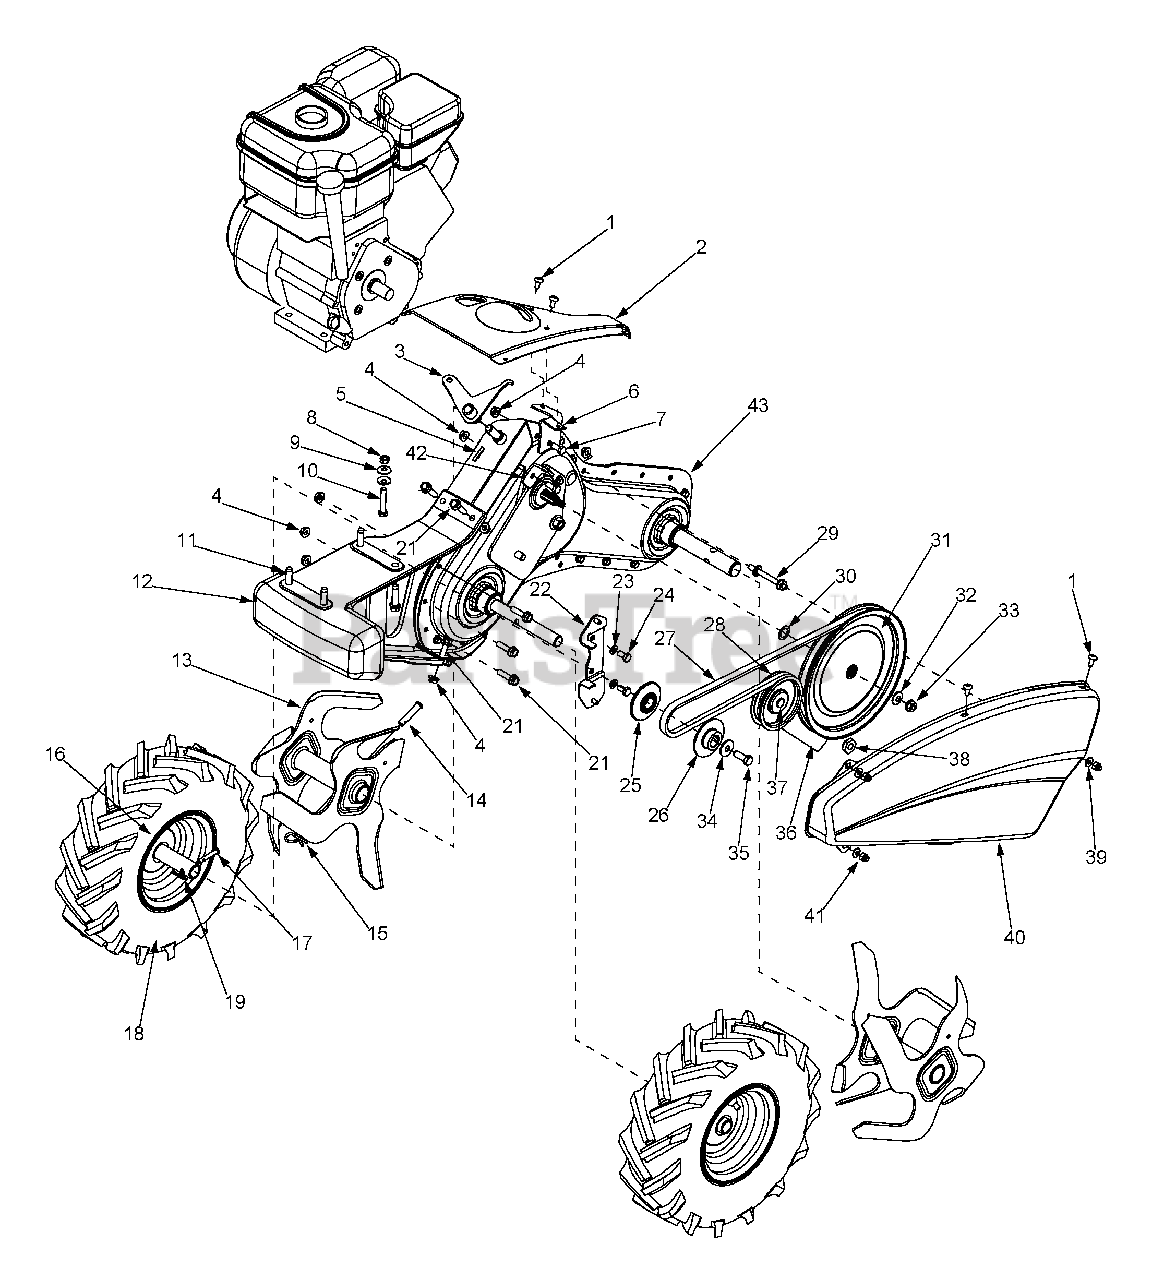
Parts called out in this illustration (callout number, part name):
1	Hex Screw 1/4-20 x.625
5	Spiral Pin
8	Hex Nut 5/16-18
9	Bell Washer.340 ID x.872 OD
10	Hex Cap Screw 5/16-18 x 1.75
11	Hex Washer Screw 3/8-16 x 1.5
12	Frame Counterweight
14	Clevis Pin
15	Cotter Pin
16	Complete Wheel Ass'y - RH (14")
17	Clevis Pin
19	Cotter Pin
21	Flange Screw 5/16-18 x 1.25
24	Hex Cap Screw 5/16-24 x.625
25	Inner Pulley Half
26	Outer Pulley Half
27	V-Belt
28	Flat Idler
29	Bolt 5/16-18 x 1/4-28 x 2.35
30	Flat Washer.635 ID x.930 OD
31	Flat Pulley
32	Spring Washer.401 ID x.870 OD
33	Flange Lock Nut 3/8-24
34	Bell Washer.396 ID x 1.140 OD
35	Hex Cap Screw 3/8-24 x 1.0
37	Hex Cap Screw 3/8-16 x 1.25
38	Shoulder Nut 7/16-20
39	Flat Washer.271 ID x.630 OD
42	Cable Bracket
43	Gear Case Assembly
